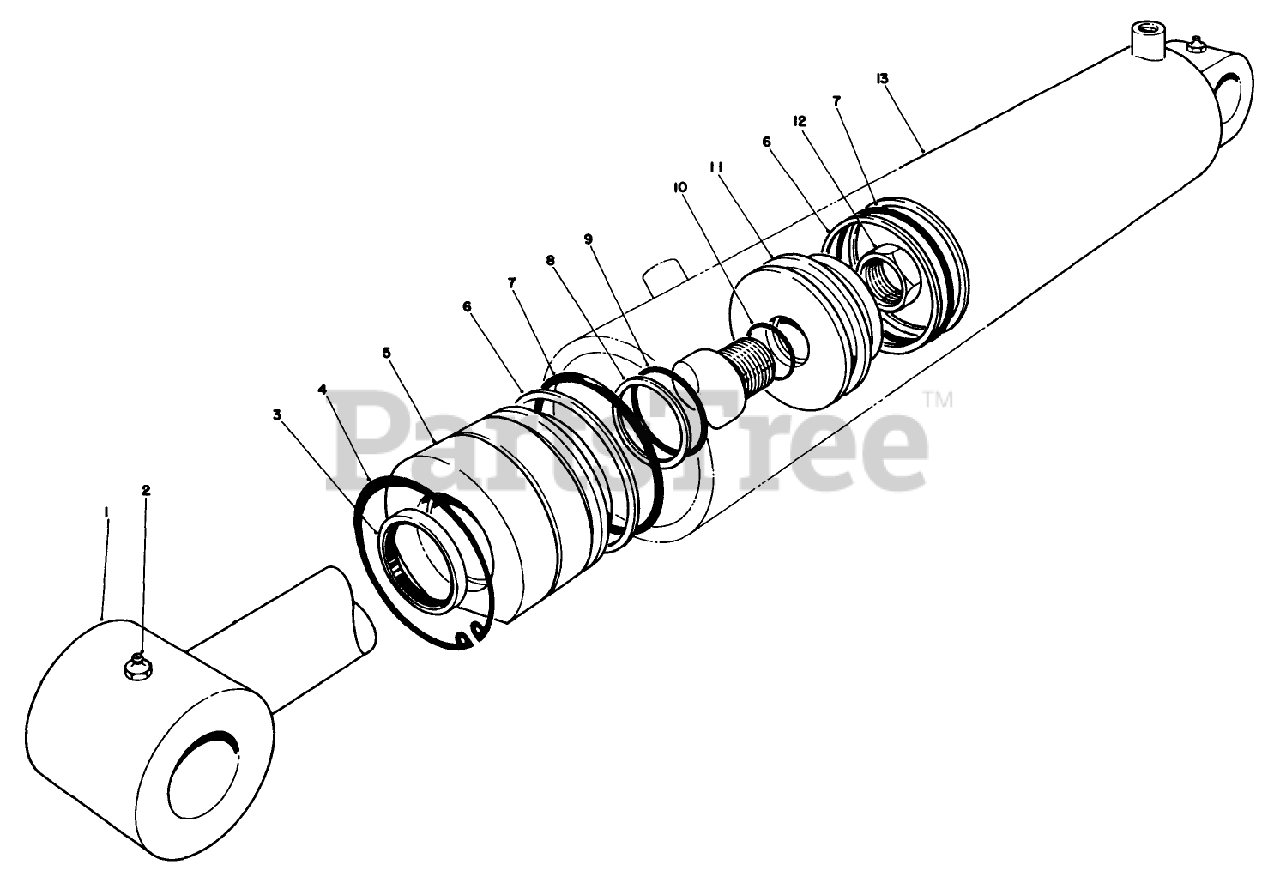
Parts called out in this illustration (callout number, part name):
1	SHAFT WITH CLEVIS
2	FITTING-GREASE
3	Dust Seal
4	RING-RETAINING
5	HEAD
6	Ring-Back-Up
8	Ring-Back-Up
11	PISTON
13	Barrel
